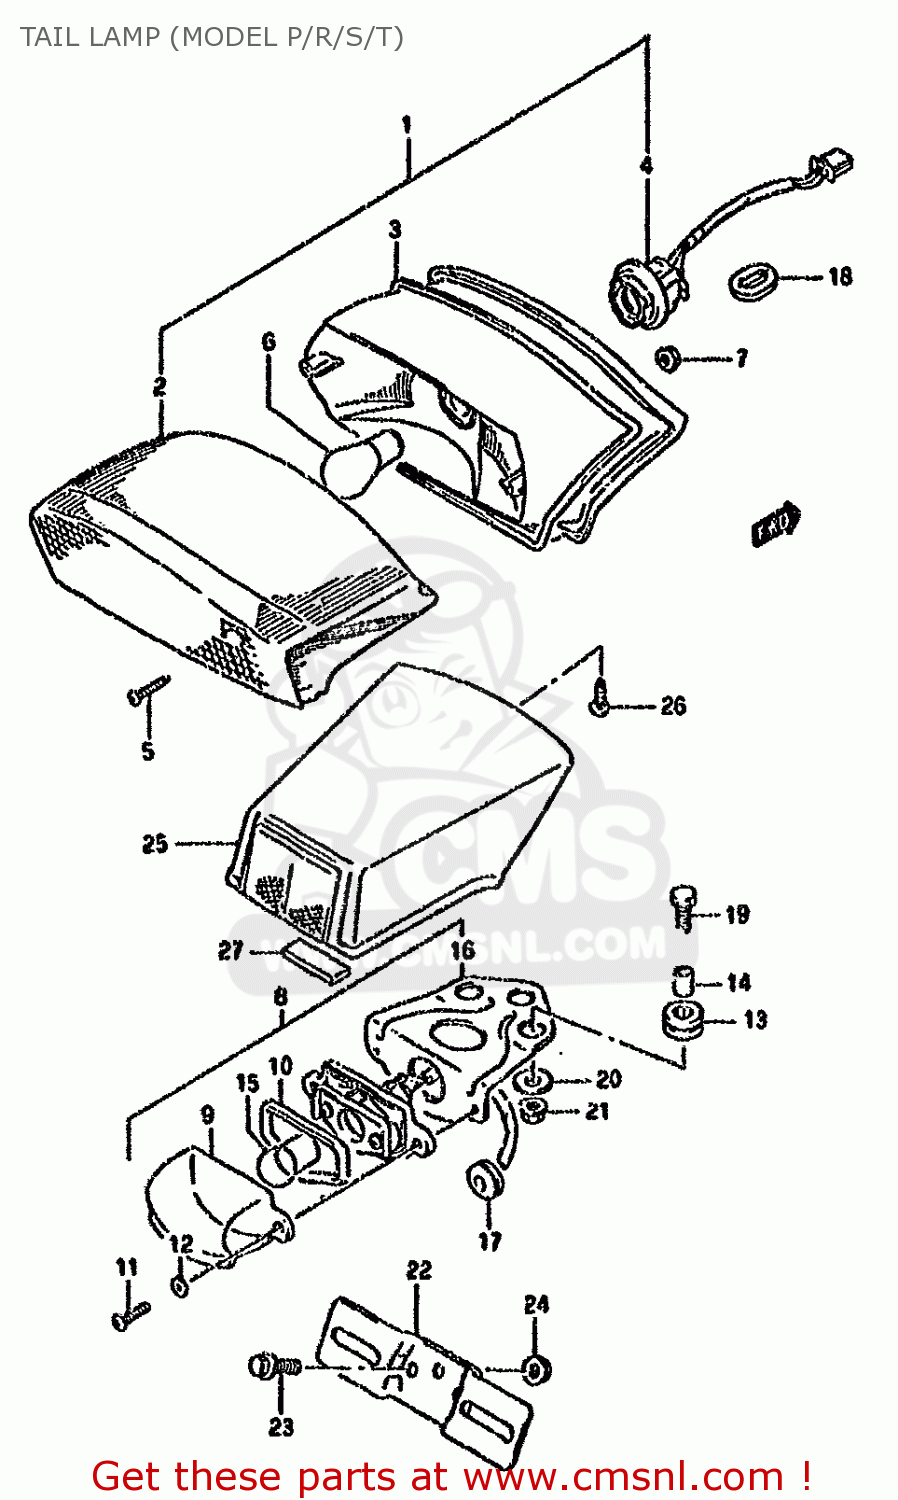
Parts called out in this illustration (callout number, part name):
1	LAMP ASSY,RR COMBINATION
2	LENS
3	GASKET (NAS)
4	SOCKET
5	SCREW
6	BULB(12V21/5W)
7	NUT
8	LAMP ASSY,LICENSE
9	LENS,LICENSE LAMP
10	GASKET,LICESE LAMP (NAS)
11	SCREW
12	WASHER
13	CUSHION,RR COMBINATION
14	SPACER
15	BULB(12V5W,BF150-40160A)
16	BRACKET
17	GROMMET
18	GROMMET
19	BOLT(6X20)
20	WASHER
21	NUT
22	BRACKET,LICENSE PLATE
23	SCREW
24	NUT
25	COVER,LICENSE LAMP
26	BOLT
27	NUT
28	REFLEX REFLECTOR,FR SIDE
29	BRACKET
30	BRACKET
31	SCREW 5X12
32	NUT
33	COVER,LICENSE LAMP
34	SCREW
35	PROTECTOR,LICENSE LAMP
